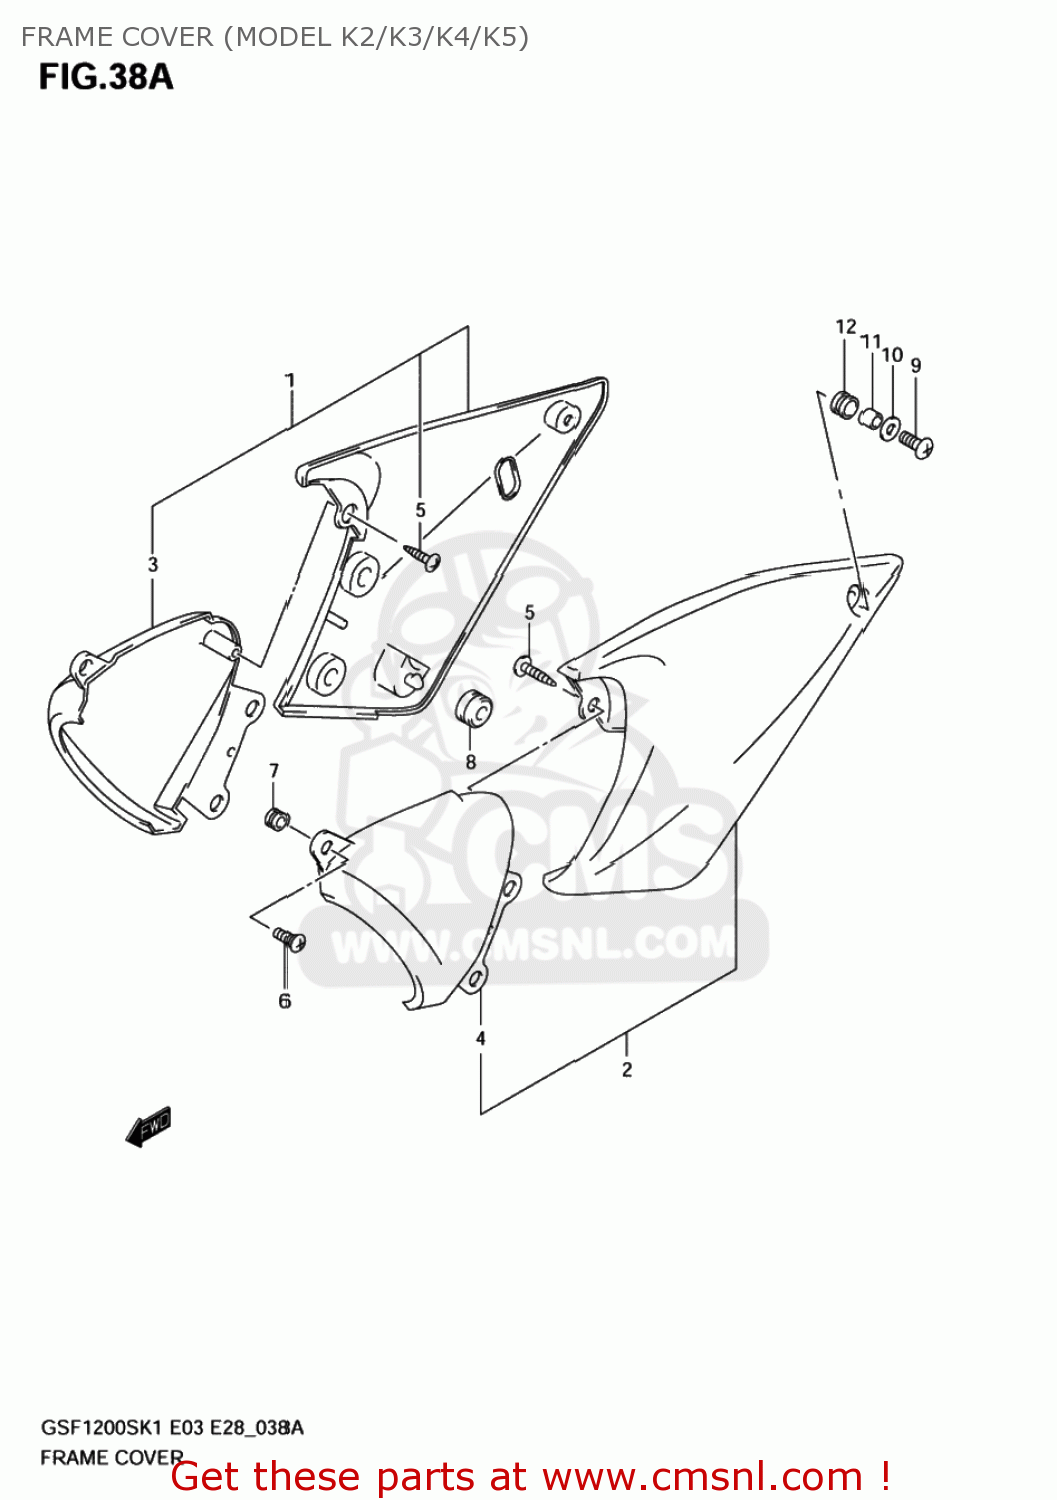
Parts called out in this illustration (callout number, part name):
1	COVER,FRAME,R(BLACK)
2	COVER,FRAME,L(BLACK)
3	COVER,FRAME FR,R
4	COVER,FRAME FR,L
5	SCREW
6	SCREW(5X16)
7	CUSHION,FRAME COVER FR
8	CUSHION
9	SCREW(6X16)
10	WASHER(6.5X18X1)
11	SPACER(6.5X9X9)
12	CUSHION
